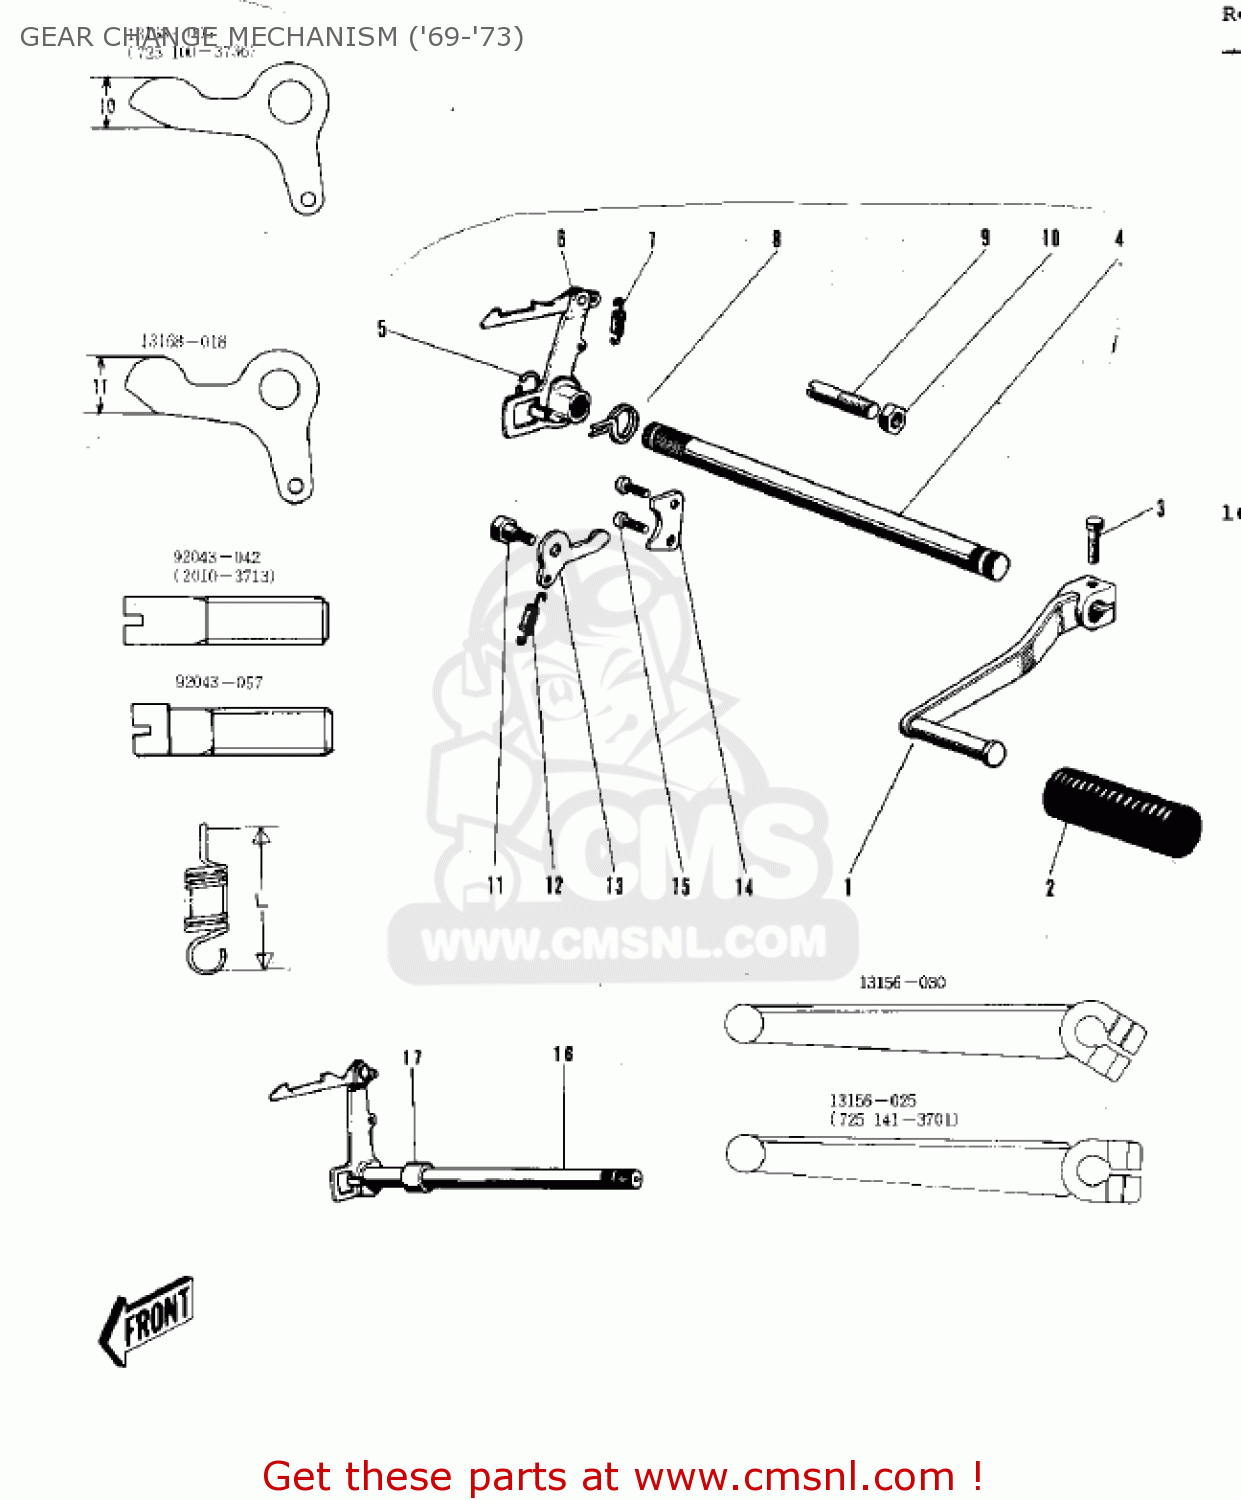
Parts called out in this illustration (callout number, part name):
1	LEVER-ASSY-CHANGE
2	RUBBER-CHANGE PEDAL
3	BOLT 6X20
4	LEVER SET-GEAR CHANGE
5	RING-SNAP
6	LEVER SET-GEAR CHANGE
7	SPRING,CHANGE LEVER
8	SPRING,TENTION
9	PIN-CHANGE PEDAL SPRG
10	NUT,8MM
11	BOLT,CHANGE DRUM LEVE
12	SPRING,CHNG DRUM LEV
13	LEVER,CHNG PDL PSTON
14	PLATE,CHANGE DRUM POS
15	SCREW-PAN HEAD,6X14
16	LEVER-COMP-CHANGE SHA
17	COLLAR
?	LEVER SET-GEAR CHANGE
